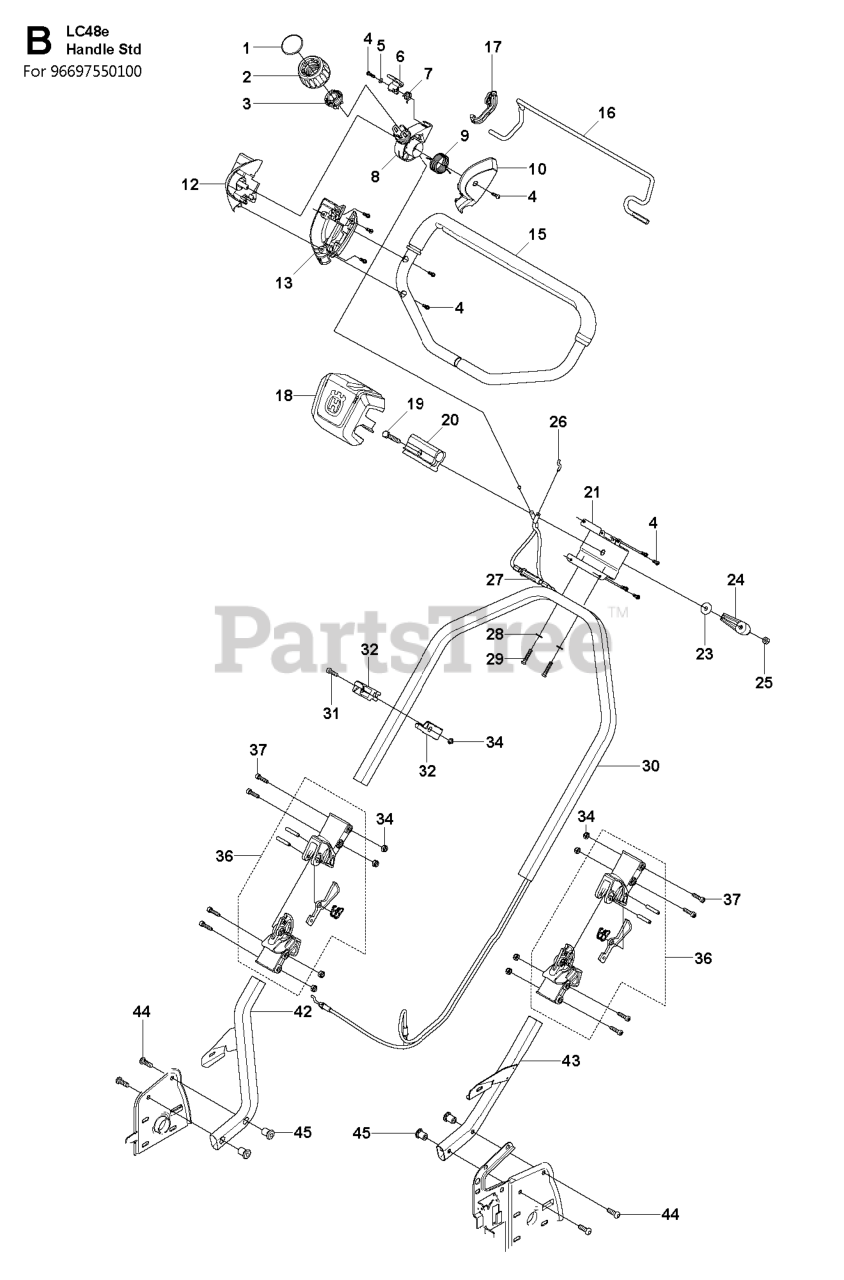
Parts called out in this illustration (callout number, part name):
5	WASHER
23	WASHER - 25X8.5X2.3
31	SCREW MC6S 6X20
37	REPL BY 725 53 74-55
